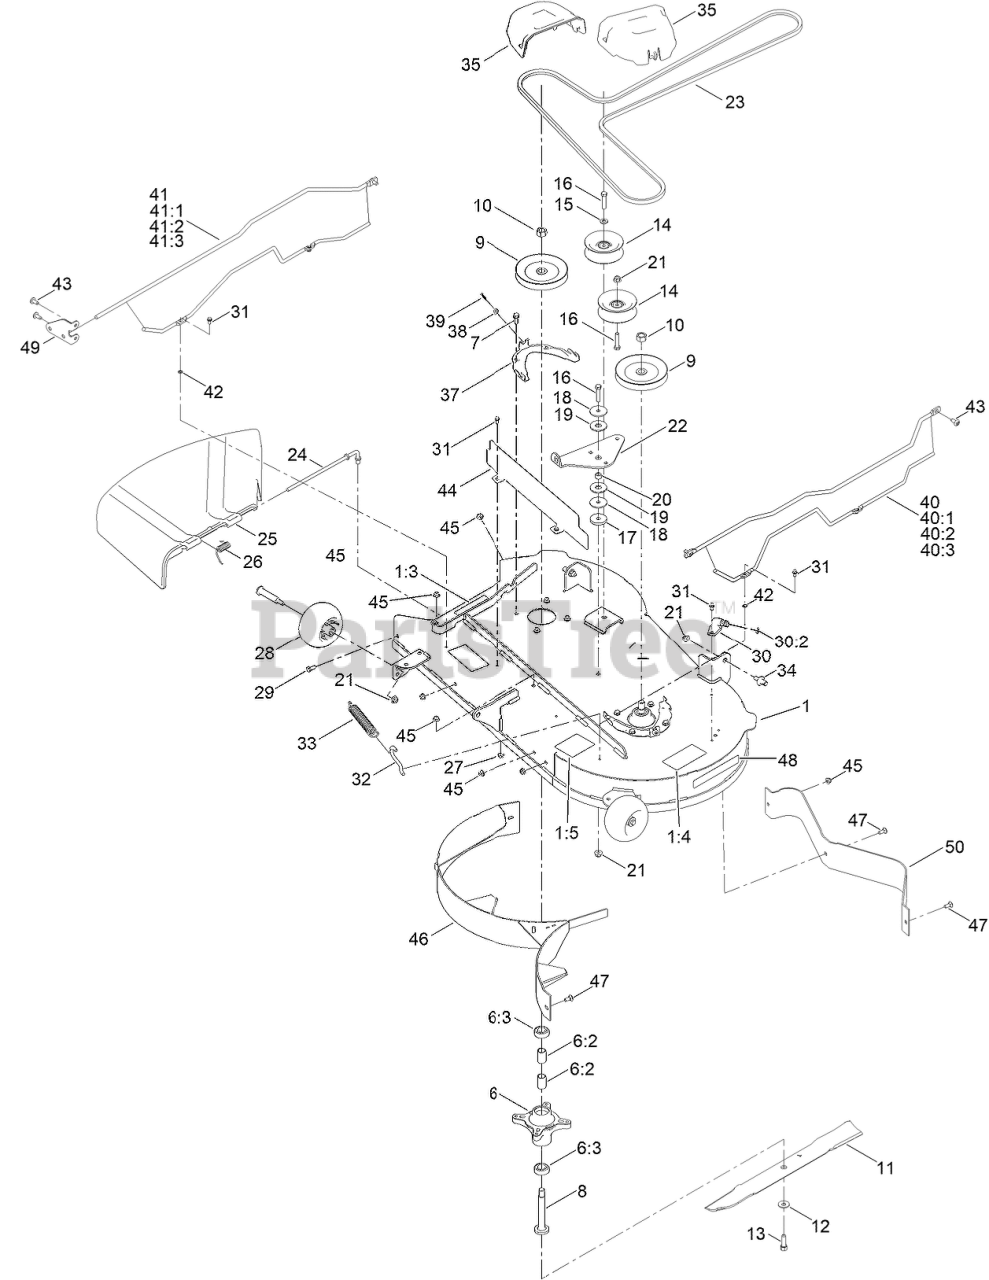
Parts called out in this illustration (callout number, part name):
1	42IN DECK AND DECAL ASM
1:3	DECAL-DANGER
1:4	DECAL-DANGER, DECK
1:5	DECAL-ROUTING, BELT
6	SPINDLE ASM
6:2	SPACER
6:3	BEARING-BALL
7	SCREW-TAPTITE
8	SHAFT-SPINDLE
9	Pulley
10	Nut-Hex
11	BLADE-MULCH
12	WASHER-BELLEVILLE
13	SCREW-HH
14	PULLEY-IDLER, FLAT
15	WASHER-FLAT
16	SCREW-HH
17	WASHER-PLAIN
18	Washer
19	WASHER-FRICTION, COMPOSITE
20	SPACER
21	NUT-HF, NI
22	ARM-IDLER
23	V-BELT
24	ROD-PIVOT
25	DEFLECTOR-DISCHARGE
26	SPRING-TORSION
27	NUT-HEX
28	ROLLER-SCALP, ANTI
29	BOLT-SHOULDER
30	FITTING-WASHOUT
30:2	O-RING
31	SCREW-HWH
32	HOOK-RETURN SPRING
33	SPRING-EXTENSION
34	PIN-DECK
35	COVER-BELT
37	BRACKET-COVER, BELT
38	SPACER-NOTCHED
39	SCREW-PPH
40	LEFT GUARD ASM
40:1	GUARD-LEFT
40:2	ROD-TOP, LEFT
40:3	ROD-SUPPORT, LOWER
41	RIGHT GUARD ASM
41:1	GUARD-RIGHT
41:2	ROD-SUPPORT, LOWER
41:3	ROD-TOP, RIGHT
42	NUT-RETAINING
44	SHIELD-FROUNT
45	NUT-HF
46	BAFFLE-RECYCLING
47	BOLT-CARR
48	DECAL-RECYCLER
49	PLATE-MOUNT, GUARD
50	DEFLECTOR
